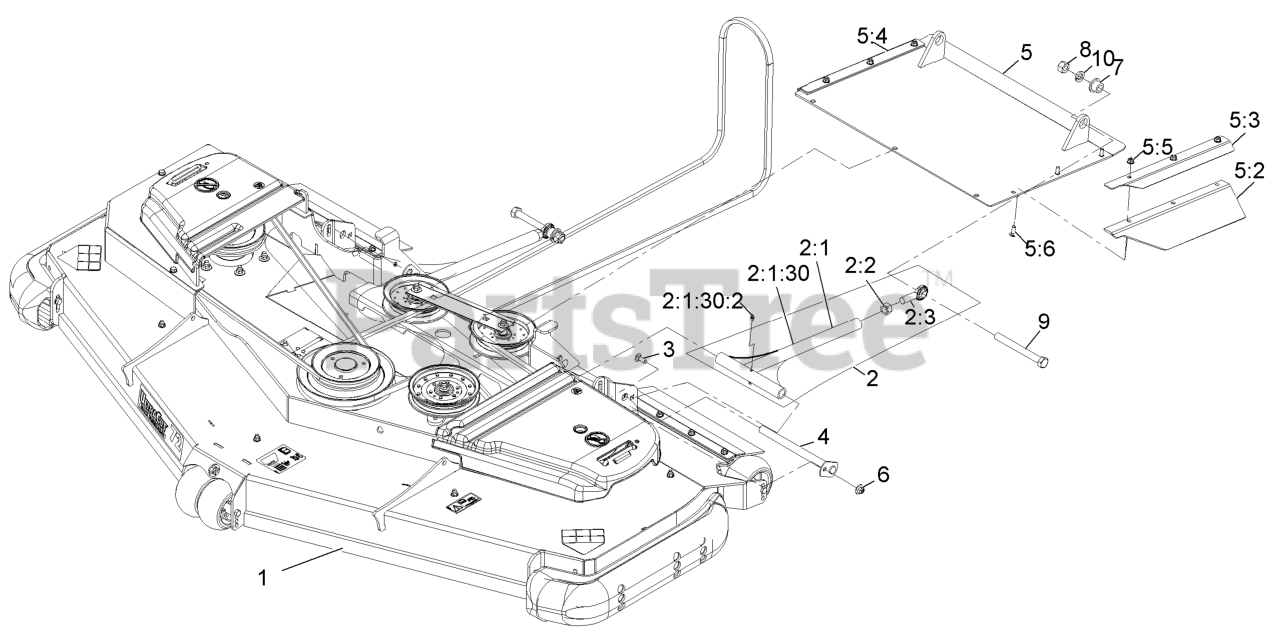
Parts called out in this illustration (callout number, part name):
1	ASM-Deck Complete Rd72
2	ASM,DECK STRUT XS 72
2:1	WLD,DECK STRUT
2:1:30	Tube And Zerk ASM
2:1:30:2	Fitting-Grease
2:2	NUT-HEX
2:3	BALLJOINT-SPHERICAL
3	BOLT-CARR
4	PIN-STRUT
5	ASM-DISCHARGE TUNNEL RD72
5:2	FLAP-RD TUNNEL SIDE
5:3	BRKT-RD TUNNEL FLAP LH
5:4	BRKT-RD TUNNEL FLAP RH
5:5	NUT-HF, NI
5:6	SCREW-CARR
6	Nut-Nyloc 3/8-16 Flg
7	BUSHING-FLANGE
8	NUT-HEX
10	WASHER-LOCK
